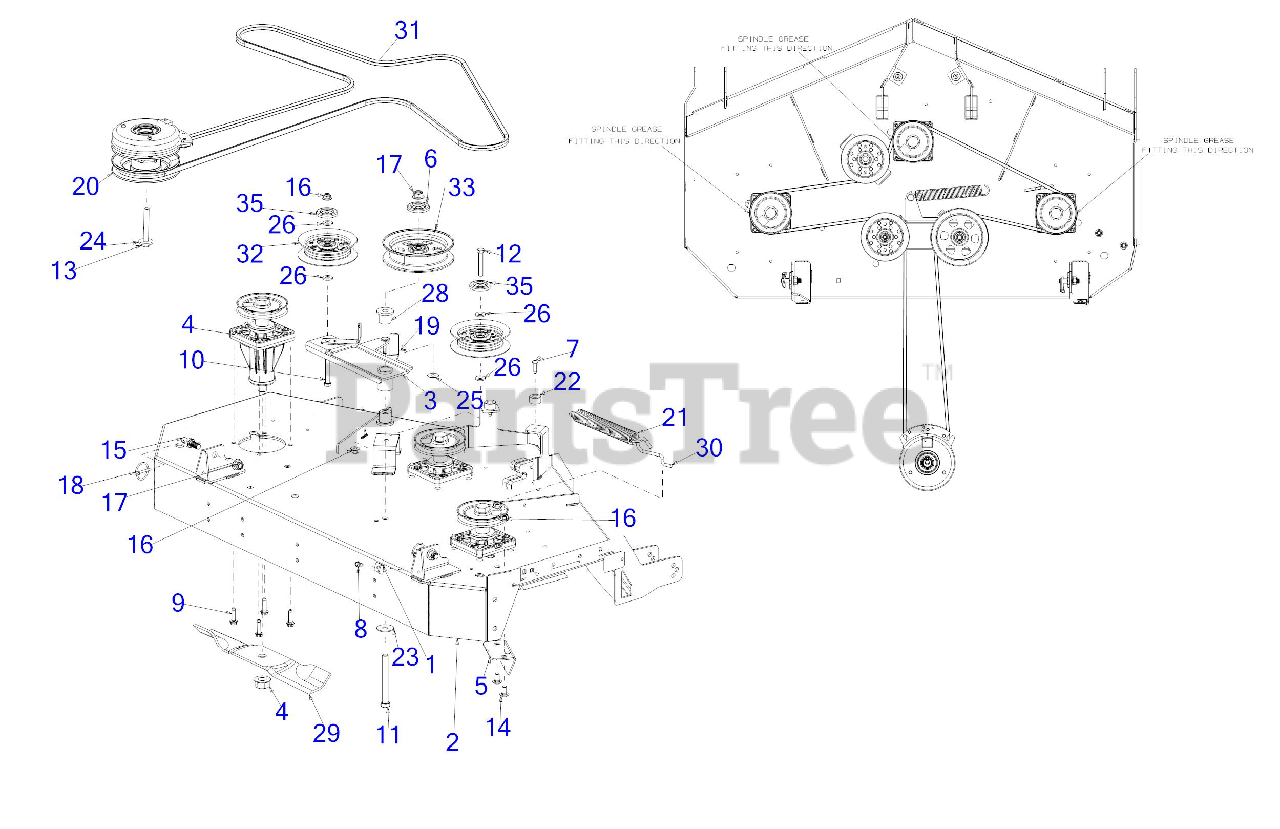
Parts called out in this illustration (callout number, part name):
1	HOOK RETAINER BRACKET
2	48" FAB DECK SHELL
3	IDLER ARM ASSEMBLY
4	SPINDLE ASSEMBLY
4	HEX FLANGE NUT 3/4
6	PULLEY CAP
7	SCREW 1/4-20 x 1.0
8	SCREW 1/4-20 X.500
9	SCREW 5/16-18 x 1.25
9	HEX SCREW WASHER 5/16-18 x 1.5
10	HEX SCREW-3/8-16X2.5 GR5
11	SCREW 1/2-13 x 4.5 GR 5
12	SCREW 3/8-16 x 2.25 GR5
13	SCREW 7/16-20 x 3.25 GR5
14	CARRIAGE BOLT 3/8-16 x .75
19	COTTER PIN 3/32
20	ELECTRIC PTO CLUTCH
21	EXTENSION SPRING
23	WASHER .51 x 1.5 x .07
24	FLAT WASHER .445 x 1.248 x .170
25	FLAT WASHER
26	FLAT WASHER
28	SHOULDER SPACER
29	17" BLADE (HI LIFT)
29	Cub Cadet 48" HI LIFT BLADE SET
29	17" HI-LIFT BLADE 0.756 ID
29	LOW-LIFT 17" BLADE (48"DECK)
29	BLADE-HI LIFT 17.0
29	17" BLADE (MULCH)
30	DECK SPRING HOOK
31	DECK BELT A SEC x 137"
31	Cub Cadet 48"Z-FORCEDECK BELT (05012)
32	IDLER PULLEY 4.0
33	FLAT IDLER PULLEY 5"
35	IDLER PULLEY CAP
